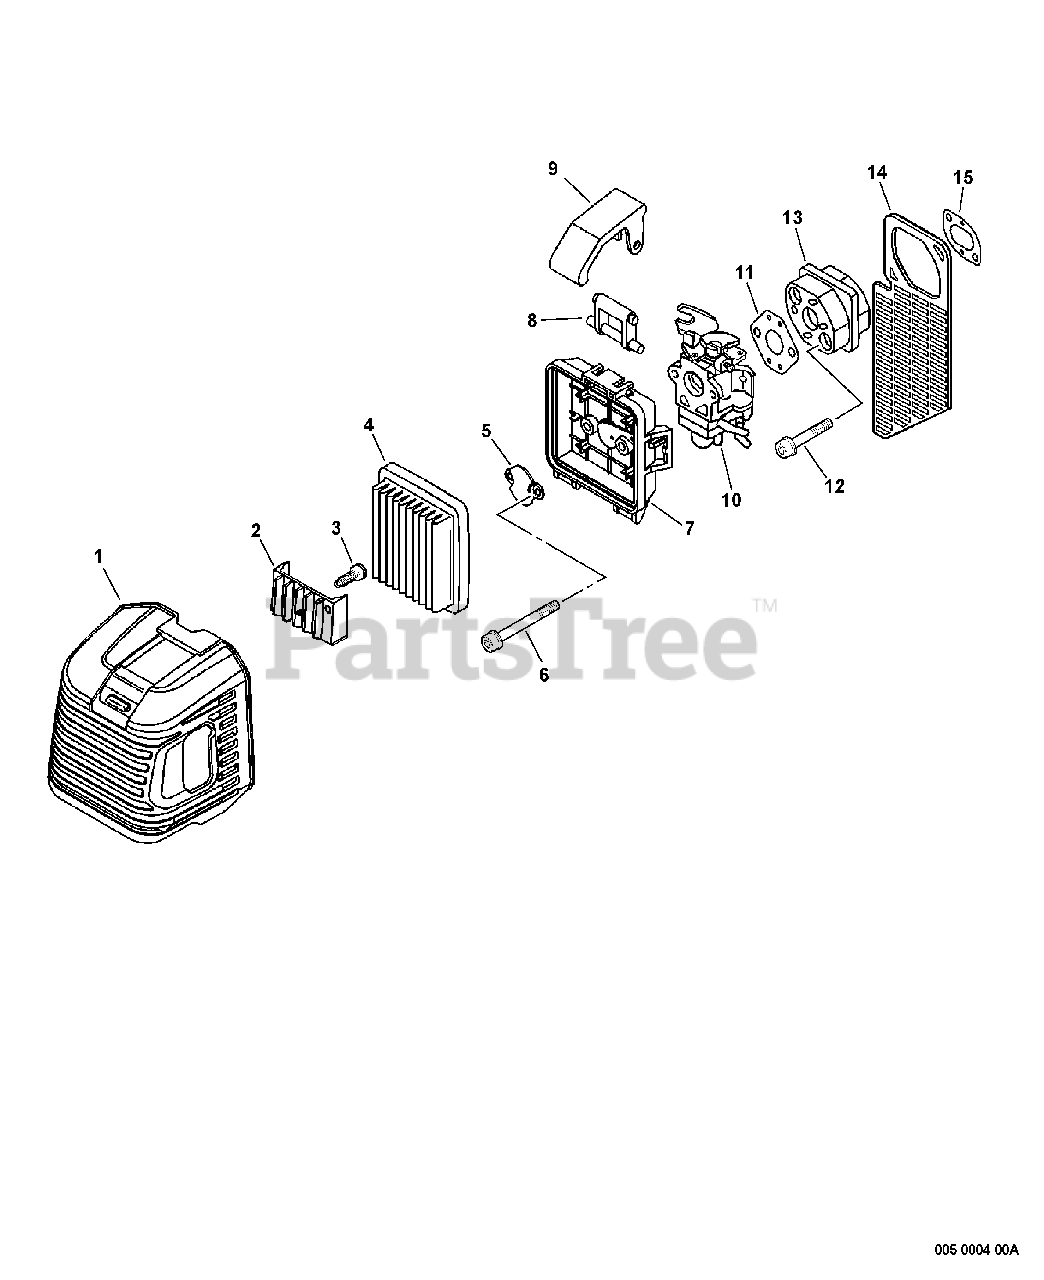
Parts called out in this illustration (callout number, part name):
1	COVER, AIR FILTER
2	PIECE, COVER
3	SCREW 4×8
4	FILTER, AIR
5	PLATE, PREVENT
6	BOLT 5×55
7	CASE, AIR FILTER
9	LATCH, FILTER COVER
10	CARBURETOR
11	GASKET, INTAKE
12	BOLT 5×25
13	INSULATOR, INTAKE
14	SHIELD, DEBRIS
15	GASKET, INTAKE
